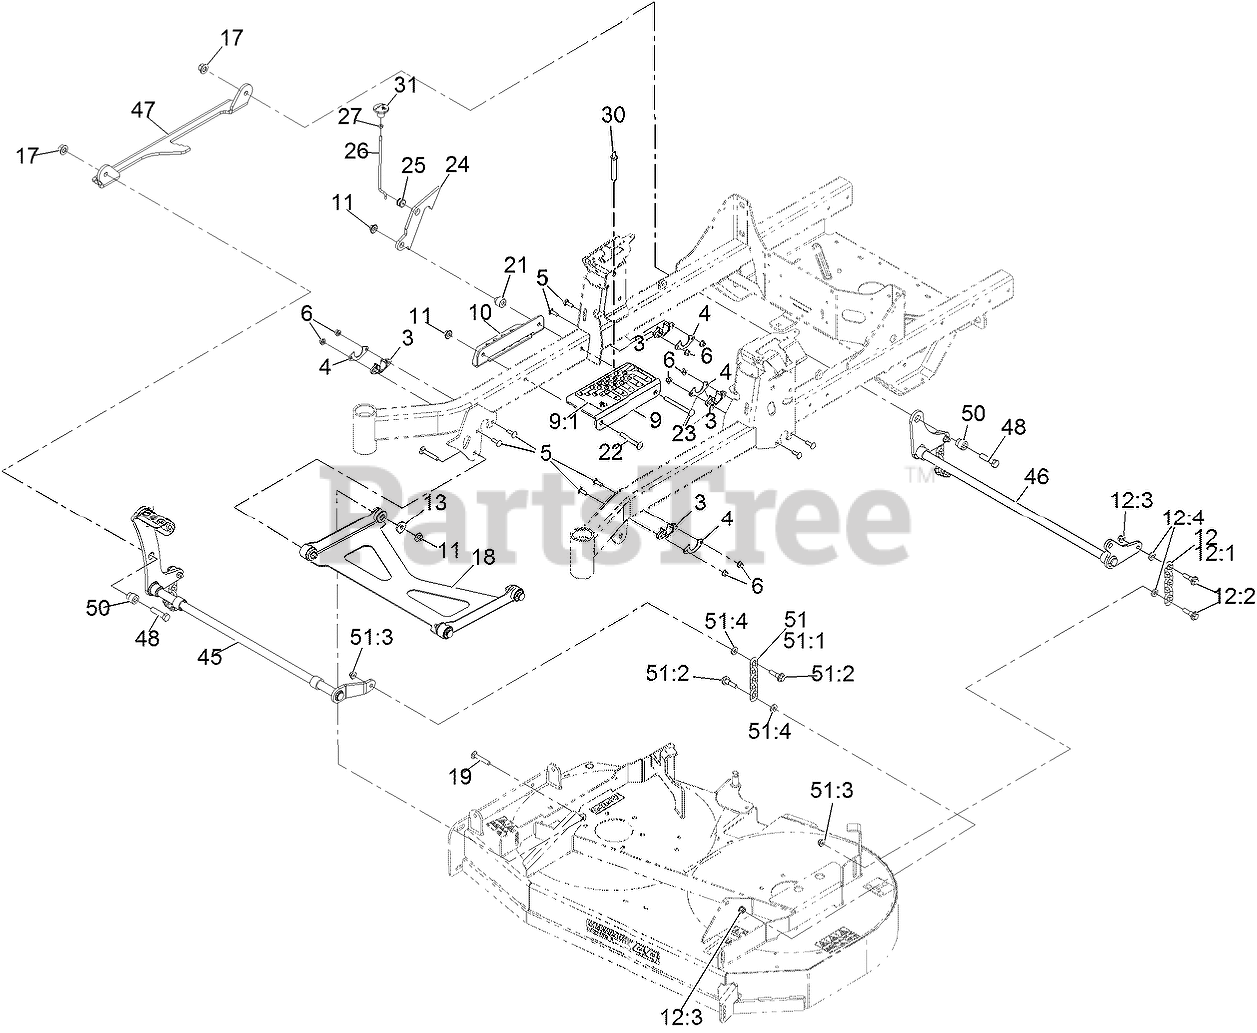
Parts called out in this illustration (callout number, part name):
3	BUSHING-FLANGE
4	GUSSET-LIFT, DECK
5	SCREW-CARR
6	NUT-HF, NI
9	BRACKET ASM
9:1	DECAL-HOC
10	ANGLE-HOC, LOWER
11	Nut-Nyloc 3/8-16 Flg
12	DECK CHAIN ASM
12:1	CHAIN-LIFT, DECK
12:2	BOLT-SHOULDER
12:3	NUT-HF, NI
17	Nut-Lock 1/2-13
18	DECK STRUT ASM
19	Bolt-Carriage 3/8-16 X 2 1/4
21	SPACER-STEPPED
22	SCREW-CARR
23	SCREW-CARR
24	PLATE-LOCK, TRANSPORT
25	GROMMET
26	ROD-LOCK, TRANSPORT
27	NUT-JAM
30	PIN-HOC
45	SHAFT-DECKLIFT FRONT
46	SHAFT-DECKLIFT REAR
47	LINK-DECKLIFT
48	SCREW-HH
50	Spacer-Stepped
51	Deck Chain ASM
51:1	CHAIN-LIFT, DECK
51:2	BOLT-SHOULDER
51:3	NUT-HF, NI
